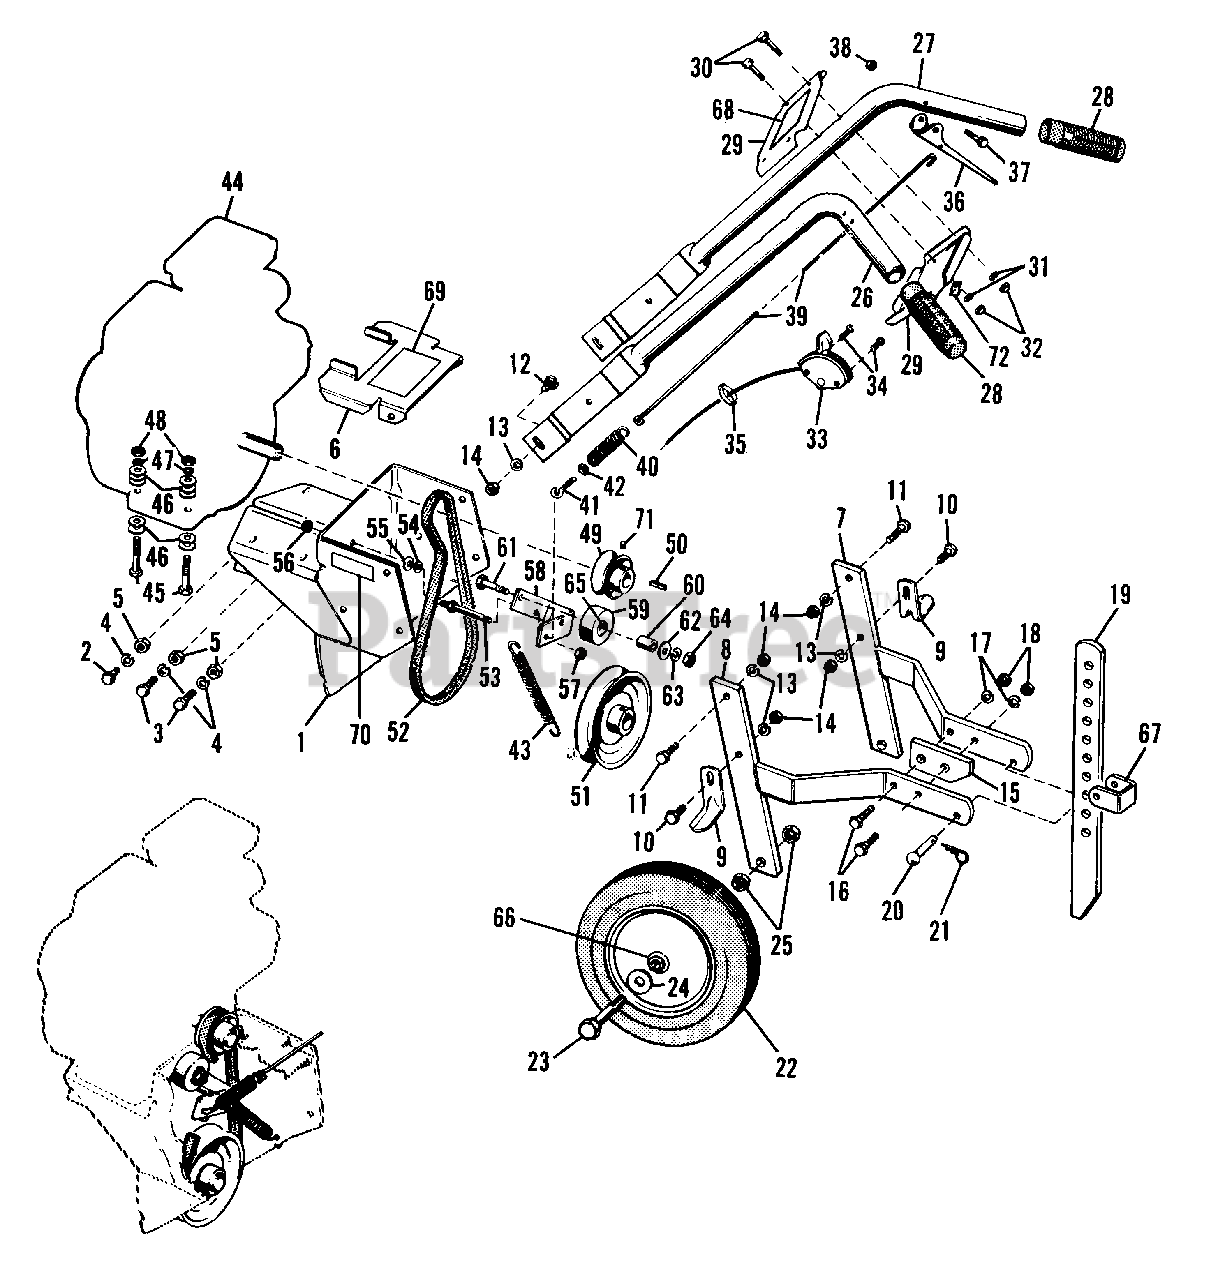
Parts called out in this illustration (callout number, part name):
1	BODY ASSY
2	CAPSCREW, Hex, 3/8-16 x 3/4
3	CAPSCREW, Hex, 3/8-16 x 1-1/4
4	LOCKWASHER, 3/8
5	NUT, Hex, Full, 3/8-16
7	SUPPORT ASSY, R.H.
8	SUPPORT ASSY, L.H.
10	CAPSCREW, Hex, 3/8-16 x 1
11	CAPSCREW, Hex, 3/8-16 x 1-1/4
12	BOLT, Carriage, 3/8-16 x 3/4
13	LOCKWASHER, 3/8
14	NUT, Hex, Full, 3/8-16
15	PLATE, Stop
16	CAPSCREW, Hex, 3/8-16 x 1-1/2
17	LOCKWASHER, 3/8
18	NUT, Hex, Full, 3/8-16
19	BAR, Depth
21	CLIP, Spring
22	WHEEL & TIRE ASSY
23	CAPSCREW, Hex, 1/2-13 x 3-1/4
24	WASHER, Plain, 1/2
25	NUT, Jam, Hex, 1/2-13
26	HANDLE, L.H.
27	HANDLE, R.H.
28	GRIP, Handle
29	COVER, Handle, Upper
30	CAPSCREW, Hex, 1/4-20 x 1-1/2
31	LOCKWASHER, 1/4
32	NUT, Hex, Full, 1/4-20
33	THROTTLE ASSY, Control
34	SCREW, Self-Tapping, #10-24 x 1
35	CLIP, Cable
36	GRIP, Clutch
37	CAPSCREW, Hex, 1/4-20 x 1-1/2
38	NUT, Hex, Full Lock, 1/4-20
39	EXTENSION, Spring
41	BOLT, Eye
42	NUT, Hex, Full, #10-24
43	SPRING (Clutch Return)
45	CAPSCREW, hex, 5/16-18 x 2
46	WASHER, Plain, 5/16
47	LOCKWASHER, 5/16
48	NUT, Hex, Full, 5/16-18
49	PULLEY, Engine
51	PULLEY, Driven
53	STUD, Pivot
54	LOCKWASHER, 5/16
55	WASHER, Plain, 5/16
56	NUT, Flange, Whiz-Lock, 5/16-1
57	NUT, Lock, Full, 5/16-18
58	CLUTCH, Lever
59	PULLEY ASSY, Idler
61	CAPSCREW, Hex, 3/8-16 x 1-1/2
62	WASHER, Plain, 3/8
63	LOCKWASHER, 3/8
64	NUT, Hex, Full, 3/8-16
72	CLIP, Cable
